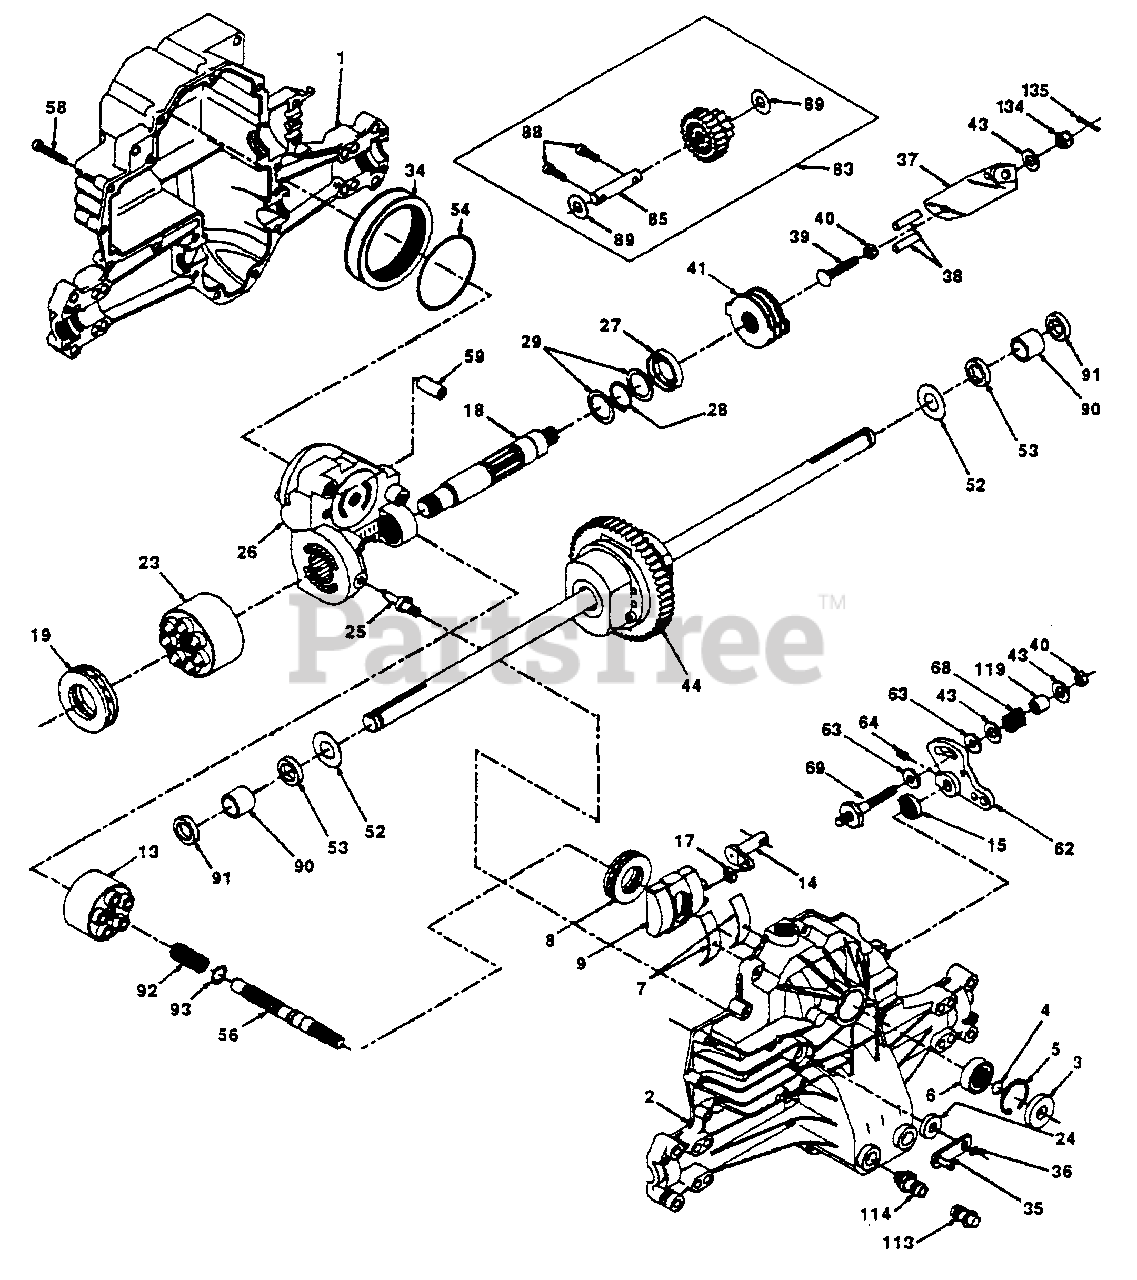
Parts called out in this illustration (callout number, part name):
1	Housing, Lower
2	Assembly, Upper Housing
4	Ring, Wire Retaining
5	Ring, Retaining
6	Bearing, Shaft Ball
7	Bearing, Cradle
8	Bearing, Thrust 30 x 52 x 13
9	Swashplate, Variable
13	Block, Cylinder Assembly
14	Arm, Trunnion
17	Guide, Slot
18	Shaft, Motor
19	Bearing, Thrust 42 x 68 x 16
23	Block, Cylinder Assembly
24	Seal, Lip 10 x 25 x 7
25	Actuator, Bypass
26	Center Section Assembly Kit
27	Seal, Lip 26 x 42 x 8
28	Ring, Retaining
29	Washer 26 x 35 x 1
34	Oil Filter Element
35	Arm, Bypass
36	Ring, Retaining
37	Arm, Actuating
38	Pin, Actuating
39	Bolt 5/16-24 x 1-3/4
40	Locknut, Hex 5/16-24 UNJC
41	Brake Rotor/Stator Kit
43	Washer 7/16 x 7/8 x .060
44	Differential Assembly
52	Washer 3/4 x 1.5 x .03
53	Seal .75 x 1.25 x .250
54	O-Ring .103 x 2.987 ID
56	Shaft, Input
58	Bolt 1/4-20 x 1.38
59	Pin .5 OD x .43 ID x .750
62	Arm, Control
63	Puck, Dampener
69	Stud 5/16-24
83	Jack Shaft Assembly
85	Jack Shaft
90	Sleeve Bearing
91	Seal, Wiper
92	Spring, Block
93	Washer, Block Thrust
113	Cap, Vent Assembly
114	Fitting, O-Ring Assembly
119	Spacer
134	Nut, Castle 5/16-24
135	Pin, Cotter
